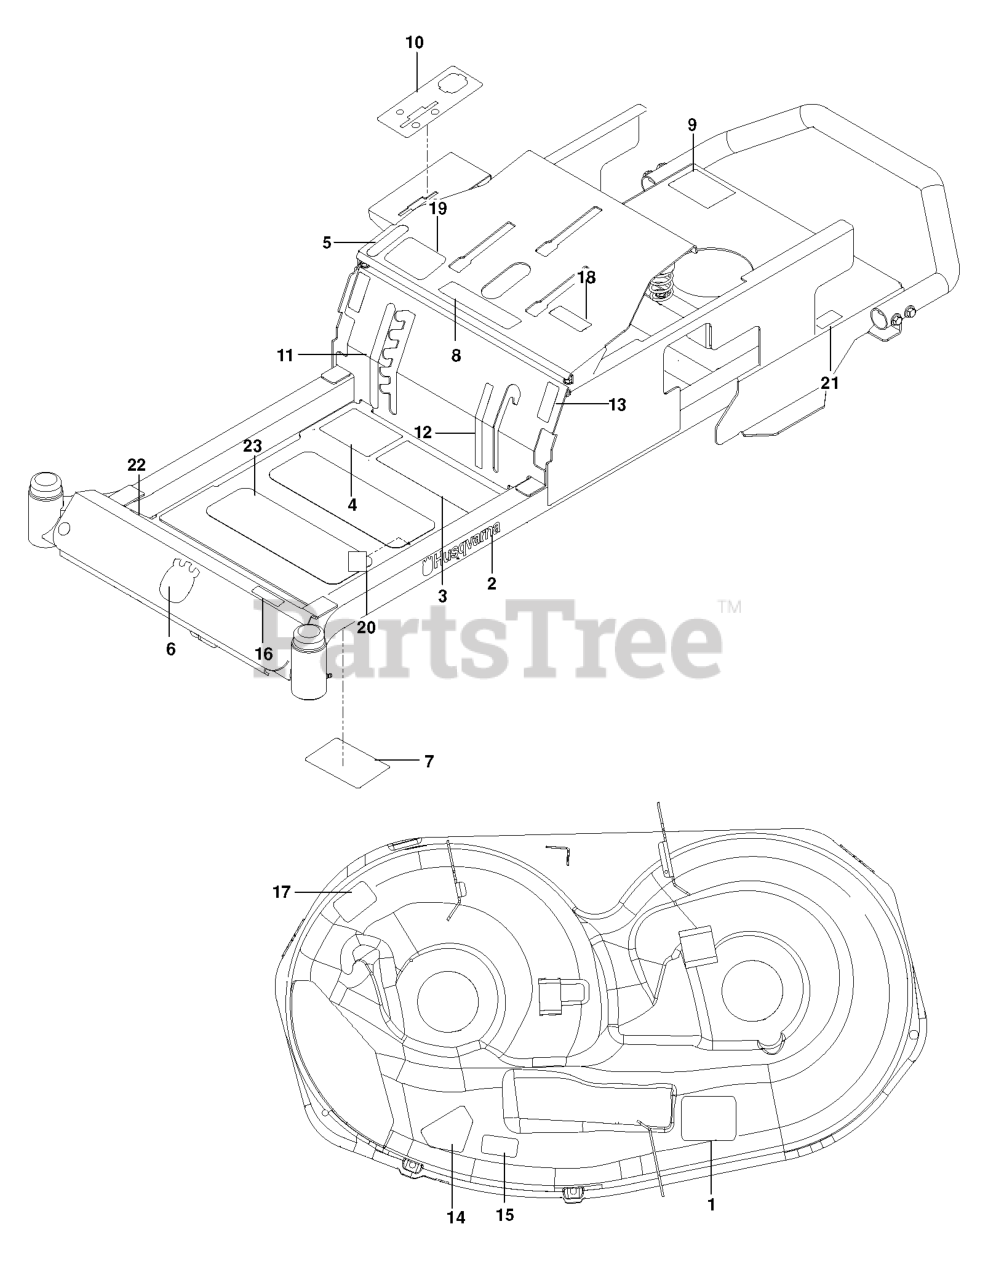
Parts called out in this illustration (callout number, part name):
1	DECAL, BELT ROUTING
2	RP.DECAL.BADGE.170MM.TEXTLOGO
3	DECAL, SAFETY WARNING
4	DECAL ZTR STARTING
5	DECAL, PARK BRAKE
6	DECAL.AUGER.HUSQ.CROWN.SNOW
7	DECAL, SERVICE
8	EURO DECAL-BATTERY WARNIN6
9	DECAL, DO NOT TOW
10	DECAL.ZTR.CONTROL.PANEL
11	DECAL, DECK HEIGHT
12	DECAL, BLADE ENGAGEMENT
13	DECAL, MOTION CONTROL
14	DECAL, CPSC
15	DECAL, EURO SEVERING
16	DECAL.RZ4219
17	DECAL.DECK.6MIL./DEF.SHLD.WARN
18	DECAL, EXITING MOWER
19	DECAL, CUSTOMER RESPNSIBILITY
20	DECAL, ECM, AUSTRALIA
21	DECAL.80.DBA.AUSTRALIA
23	ANTI-SKID PAD
